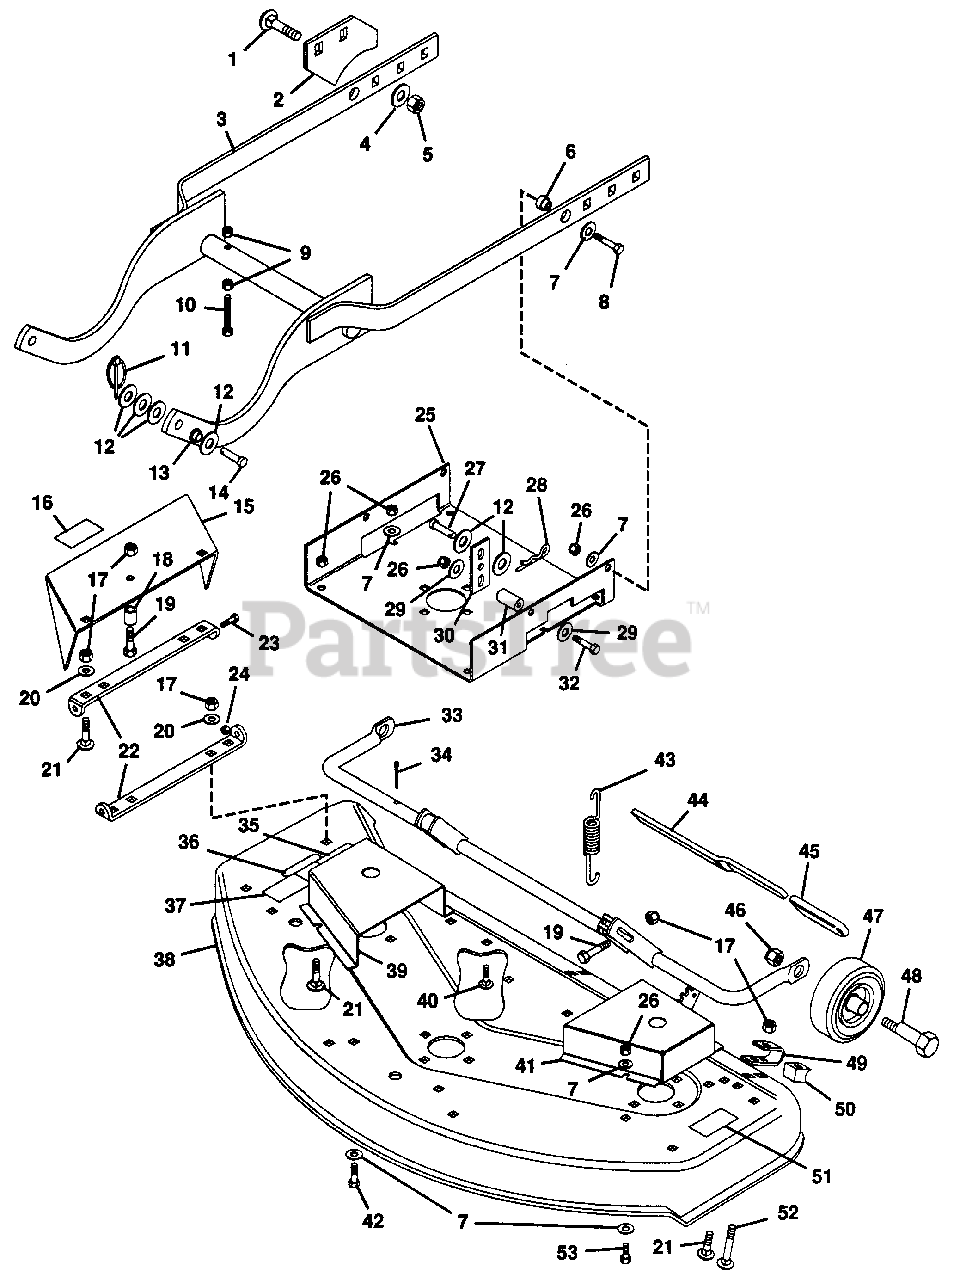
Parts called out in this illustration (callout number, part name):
1	Bolt, Carriage 1/2-13x1.25
2	Plate, Cam
3	Weldment, Drag Arm
4	Washer, Flat .531x1.250x.100
5	Nut, Lock 1/2-13
6	Bush., Flg. .344x1.00x.670 Stl.
7	Washer, Flat .344x.688x.065
8	Bolt, Hex 5/16-18x1.25
9	Nut, Lock 5/16-18
10	Bolt, 5/16-18x2.5 All Thd.
11	Pin, Klik
12	Washer, Flat .531x1.063x.095
13	Bush., Flg. .512x.750x.459 Ny.
14	Pin, Clevis .50x1.330
15	Chute, 40" Flip-Up
16	Decal, Caution
17	Nut, Lock 3/8-16
18	Stop, Chute
19	Bolt, Hex 3/8-16x1.50
20	Washer, Flat .406x.812x.065
21	Bolt, 3/8-16x1 Rd Hd Sq Nk
22	Bracket, Chute 40" Mower
23	Bolt, Hex 1/4-20x.875
24	Nut, Lock 1/4-20
25	Channel
26	Nut, Lock 5/16-18
27	Pin, Clevis .50x.875
28	Pin, Cotter Hair
29	Washer, Flat .313x.875x.065
30	Link
31	Bushing, Link
32	Bolt, Hex 5/16-18x2.50
33	Weldment, Axle
34	Pin, Cotter .125x1.25
35	Decal, Warning Eye
36	Decal, Width of Cut
37	Decal, Danger Foot
38	Weldment, 40" Deck
39	Cover, Belt R.H.
40	Bolt, 5/16-18x1.12 Rd Hd Sq Nk
41	Cover, Belt L.H.
42	Bolt, Hex 5/16-18x1.00
43	Spring, 40 and 50 Inch Mower
44	Lever, Height of Cut
45	Grip, Handle
46	Nut, Lock 1/2-13
47	Wheel, Gauge
48	Bolt, Eccentric
49	Bracket, Axle Support
50	Stop, Nylon
51	Decal, Danger Hand
52	Bolt, 3/8-16x2 Rd Hd Sq Nk
53	Bolt, Hex 5/16-18x1.00
